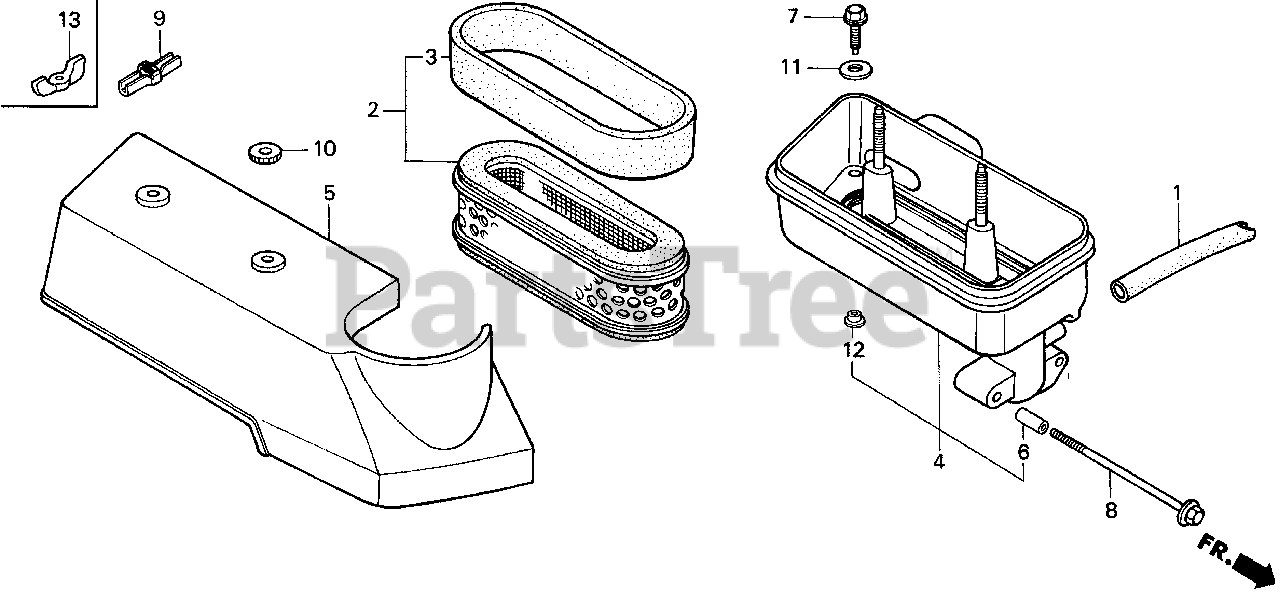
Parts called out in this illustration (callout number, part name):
1	TUBE, BREATHER
2	ELEMENT, AIR CLEANER
3	FILTER (OUTER)
4	HOUSING, AIR CLEANER
5	COVER, AIR CLEANER *R8* (BRIGHT RED)
6	COLLAR, AIR CLEANER
7	BOLT, FLANGE (5X16)
8	BOLT, FLANGE (5X83)
9	WINGNUT, AIR CLEANER COVER
9	WINGNUT (6MM)
11	WASHER, STOPPER
12	COLLAR, GEARSHIFT LEVER SETTING
13	WINGNUT, TOOL BOX SETTING
